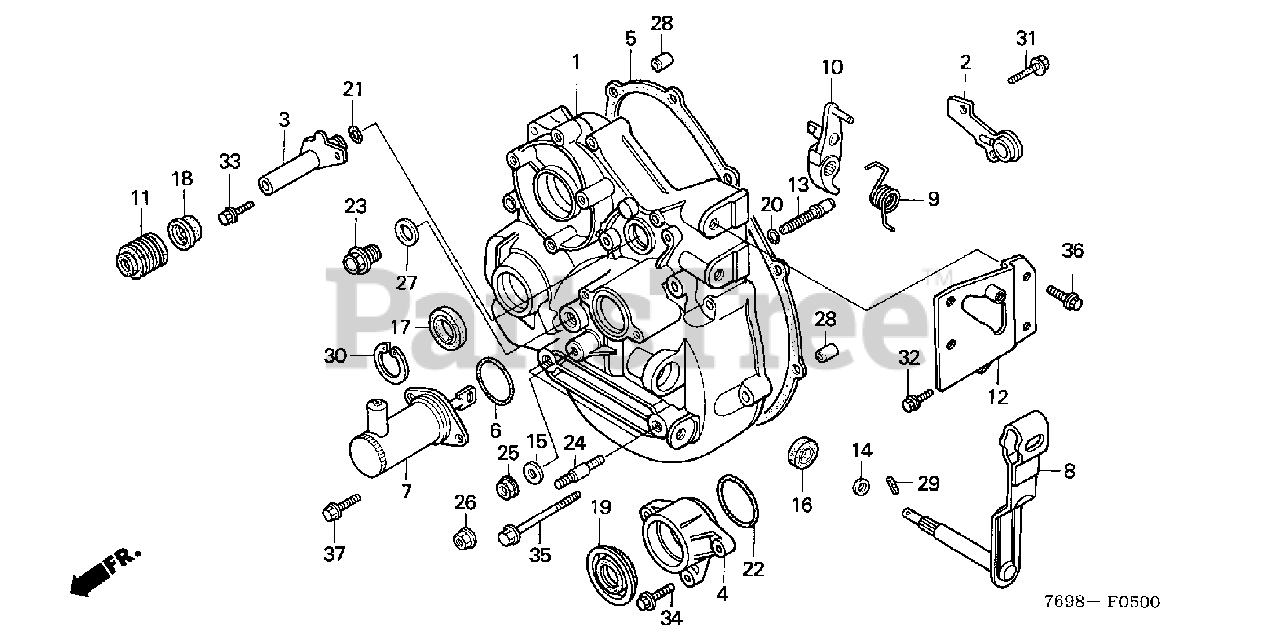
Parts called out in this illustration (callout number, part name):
1	COVER, CLUTCH
2	PLATE, OIL GUIDE
3	HOLDER, SHIFT PIECE SHAFT
5	GASKET, CLUTCH COVER
6	O-RING (37.5X2)
7	DAMPER ASSY., CLUTCH
8	LEVER, CLUTCH
9	SPRING, CLUTCH LEVER
10	CAM, CLUTCH LIFTER
11	BOOT, SHIFT SHAFT
12	BRACKET, CHANGE LEVER HOLDER
13	BOLT, ADJUSTING (8MM)
14	WASHER, THRUST (10X16)
15	WASHER (8MM)
16	OIL SEAL (14X24X6) (ARAI)
17	OIL SEAL (22X34X7)
18	OIL SEAL (14X24X11.5)
20	O-RING (6.8X1.9)
21	O-RING (21.5X1.5)
23	BOLT, DRAIN PLUG (14MM)
24	BOLT, STUD (10X25)
25	NUT, FLANGE (8MM)
26	NUT, FLANGE (10MM)
27	WASHER, DRAIN PLUG (14MM)
28	PIN A, DOWEL (10X16)
29	PIN, SPRING (3X16)
30	CIRCLIP (INNER) (34MM)
31	BOLT, FLANGE (6X16)
32	BOLT, FLANGE (8X20)
33	BOLT, FLANGE (8X22)
35	BOLT, FLANGE (8X55)
36	BOLT, FLANGE (10X25)
37	BOLT, FLANGE (6X16)
